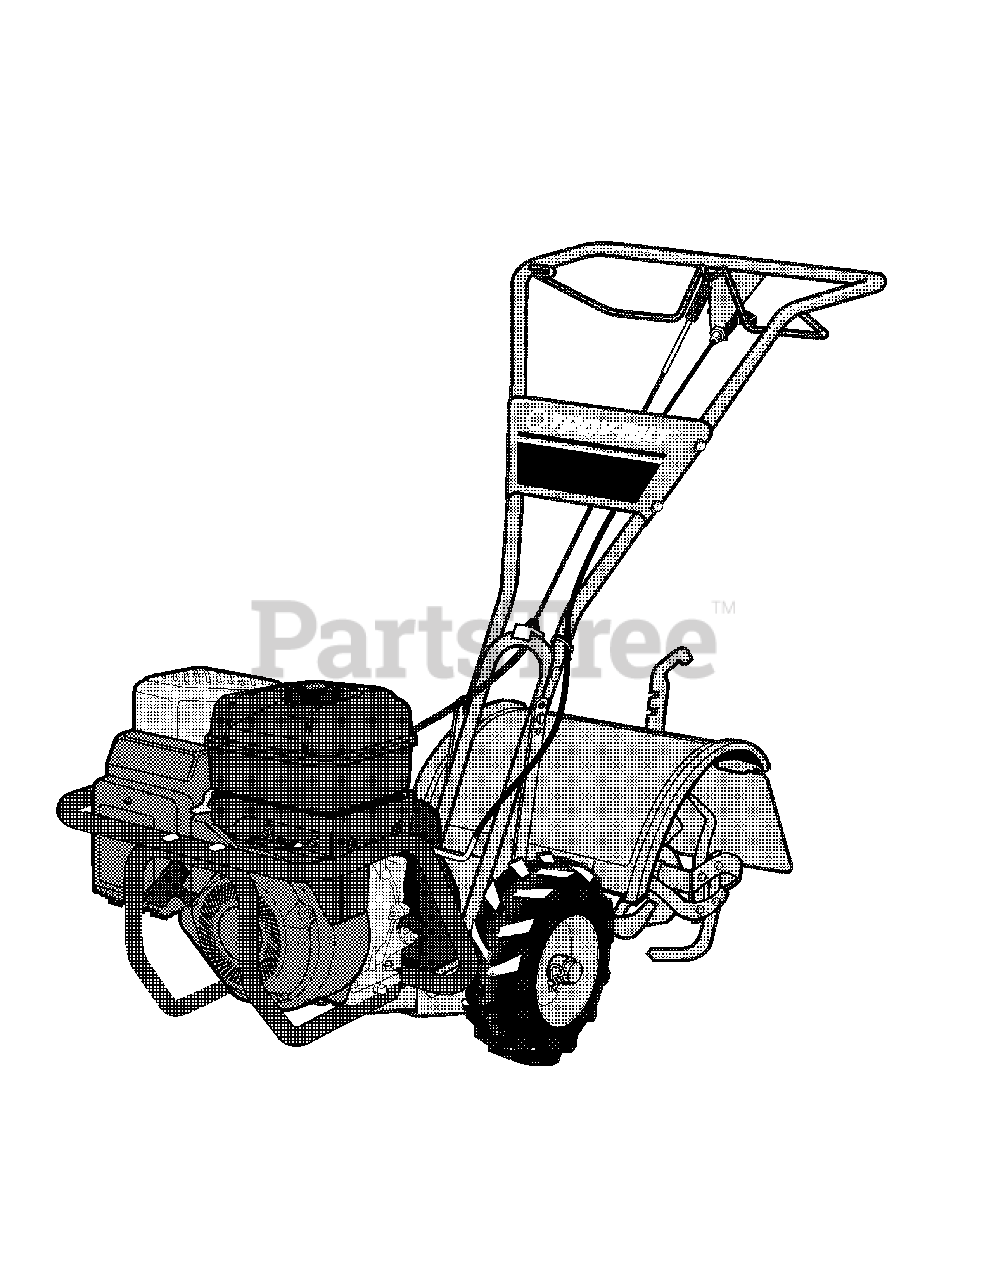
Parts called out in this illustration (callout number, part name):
NA	Pre Filter
NA	Tines-Inner
NA	Rim
NA	Tire
NA	Foam Grip
NA	Handle Knob
